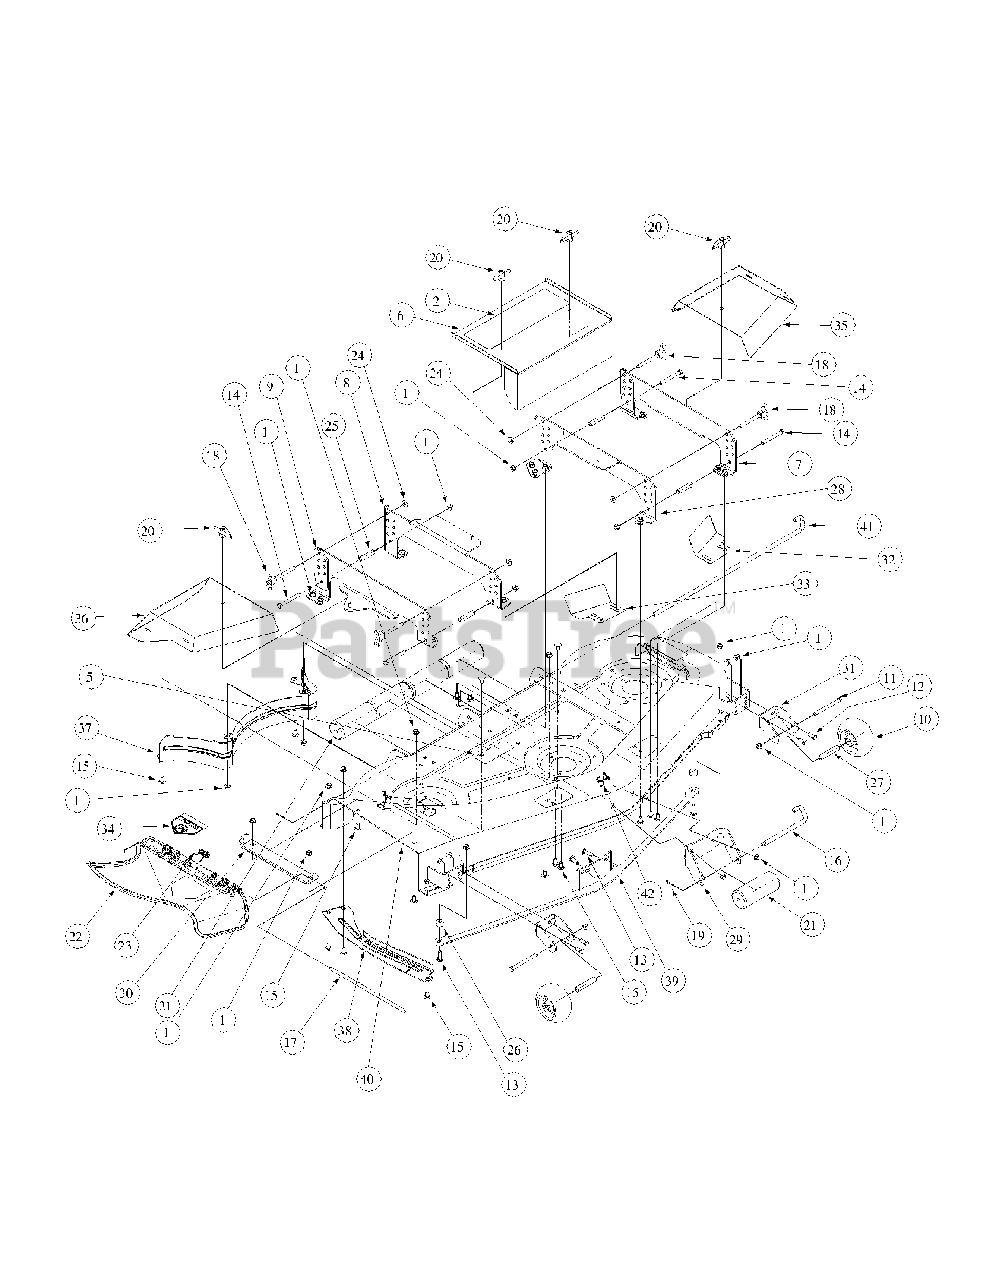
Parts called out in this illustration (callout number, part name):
1	Nut, Hex, 3/8-16 Flange Lock
2	Label, MTD Pro 54
3	Decal, Rotating Blade
4	Decal, Warning Safety
5	Decal, Warning Shield Missing
6	Cover, Belt Center
7	Hanger Assembly, Outer Left Handle
8	Hanger Assembly, Inner Right Handle
9	Hanger Assembly, Outer Right Handle
10	Wheel, Complete, 5.00 Diameter
11	HHCS, 3/8-16, 4.25
12	HHCS,3/8-16, .88
13	Carrige Screw, 3/8-16x1.25
14	HHCS, 3/8-16, 3.25
15	Carrige Bolt, 3/8-16 x .75 LG
16	Roller Pin, 1/2 Diameter x 7.31 LG
17	Pin Hinge, .375 x 12.93
18	Pin, Quick Release, 3/8 Dia. x 3.1
19	Cotter Pin, 1/8 x 1.0
20	Knob Assembly, Wingnut 5/16-18
21	Front Roller
22	Deflector Chute
23	Torsion Spring
24	Flat Washer, .385 IDx.870 ODx.092
25	Spacer, Stop Deck
26	Spacer, .406 ID x 1.00 OD x .38
27	Spacer Wheel
28	Hanger Assembly, Inner Left Hand
29	Front Roller Bracket
30	Mounting Bracket, Chute
31	Castor Bracket
32	Filler Plate, Left Handle
33	Filler Plate, Right Handle
34	Decal, Danger, Hands and Feet
35	Cover Belt, Left Hand
36	Cover Belt, Right Hand
37	Baffle, Right Rear, Inner
38	Finger Guard Assembly, 54"
39	Front Bar Assembly, 54"
40	Mower Deck Assembly
41	Roller Pin
42	Decal, 54"
